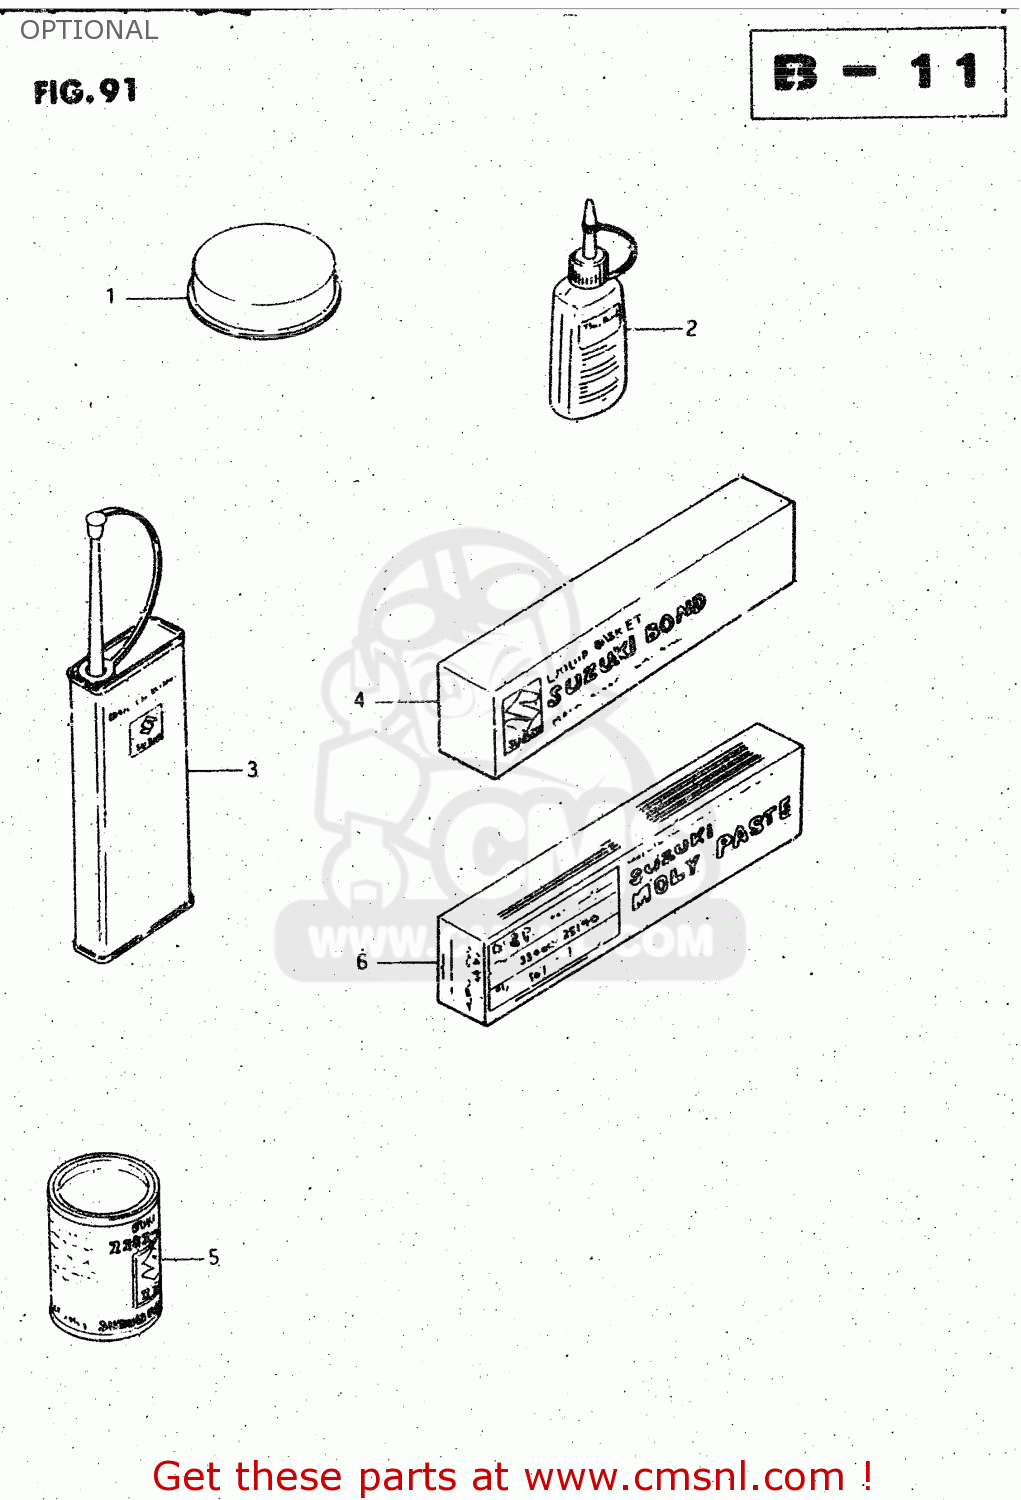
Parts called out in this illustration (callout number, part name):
1	GREASE,PBC FOR BRK PAD 20G
2	THREAD LOCK SUPER(1360)
3	THREAD LOCK NO.1401 CLEAR 200G
4	SUZUKI BOND (1216)
5	GREASE(C)EP2 LITHIUM 150G
6	SUZUKI MOLY PASTE
